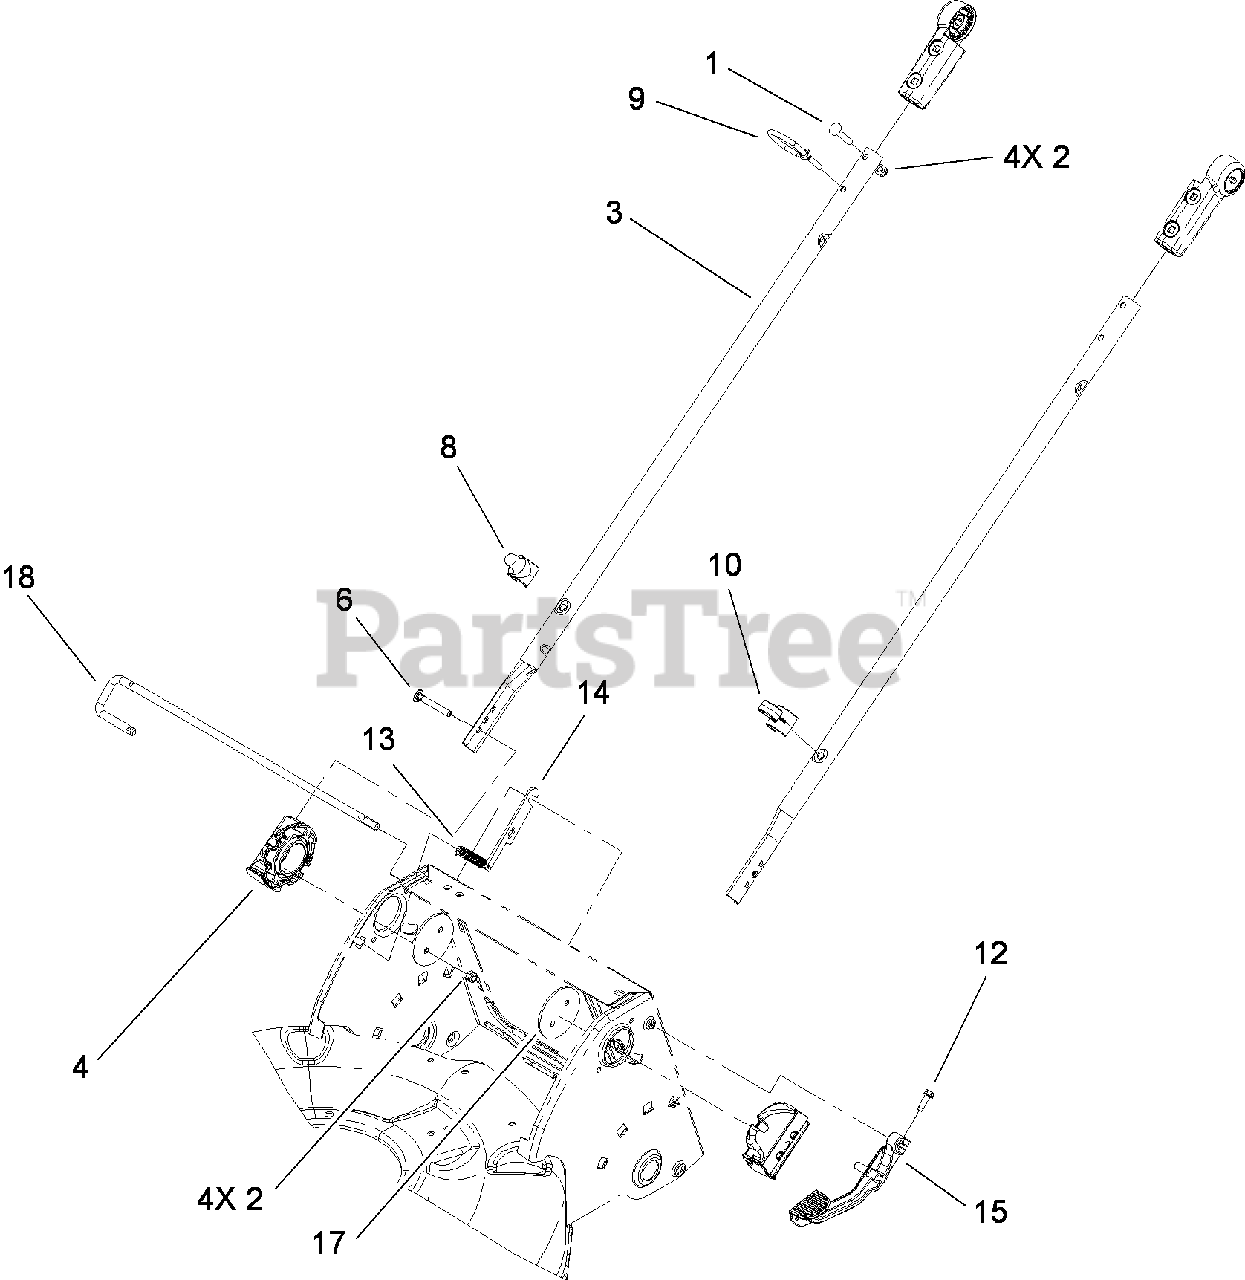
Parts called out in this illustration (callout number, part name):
1	SCREW-CARR
2	NUT-LOCK, NI
4	MOUNT-HANDLE, LOWER
8	GUIDE-ROPE, LOWER
9	GUIDE-ROPE, UPPER
10	Guide-Cable
12	SCREW-HWHTF
13	SPRING-EXTENSION
14	PLATE-RELEASE ROD
15	LEVER-RELEASE
18	ROD-HANDLE RELEASE
